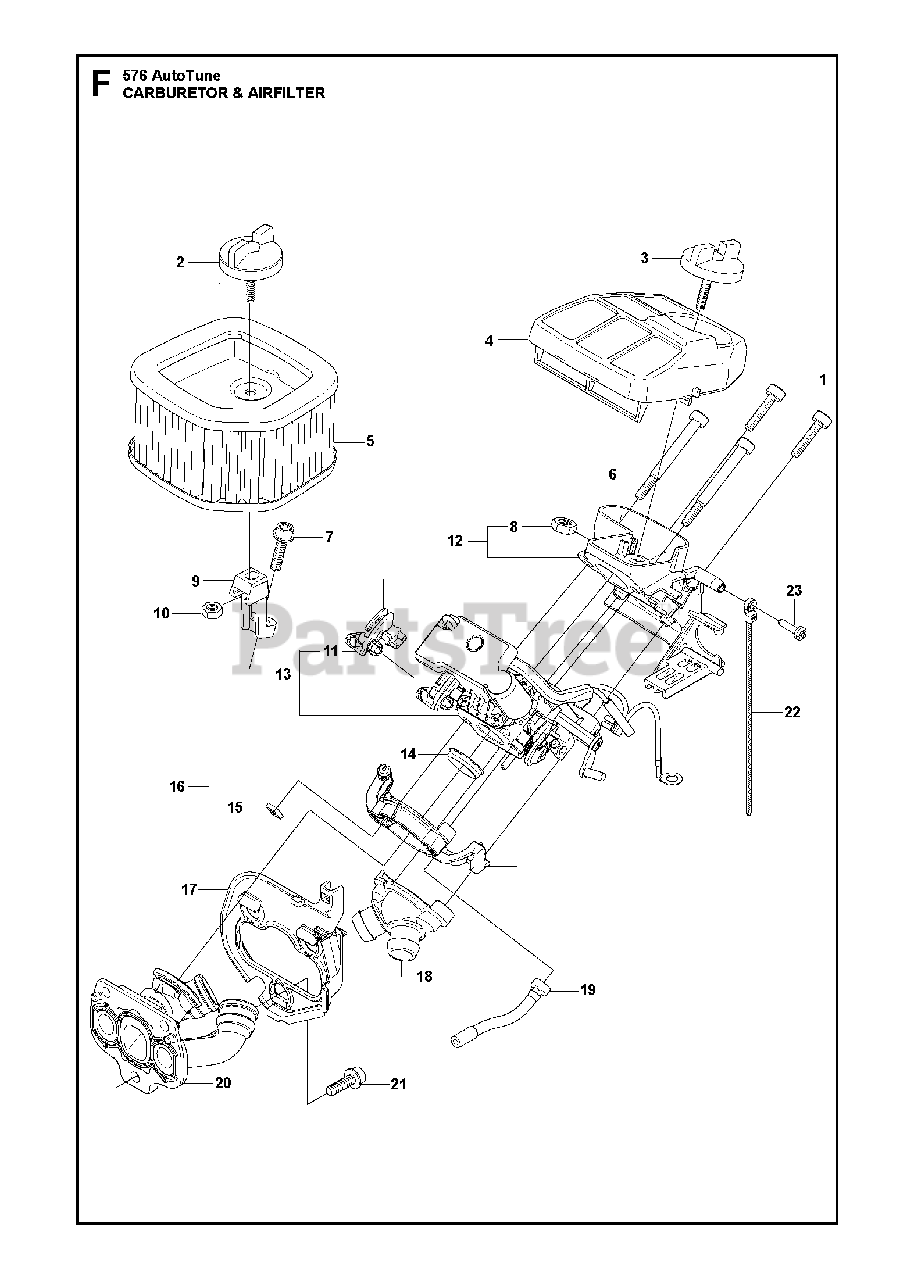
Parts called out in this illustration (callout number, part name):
4	AIR FILTER
4	RP AIR FILTER
4	%AIR FILTER
5	AIR FILTER
5	AIR FILTER 575 AUTOTUNE
6	SCREW 4X46
8	NUT
10	NUT
11	THROTTLE LEVER ASSY
12	FILTER HOLDER
13	CARBURETTOR C1M-EL40H
15	NUT
